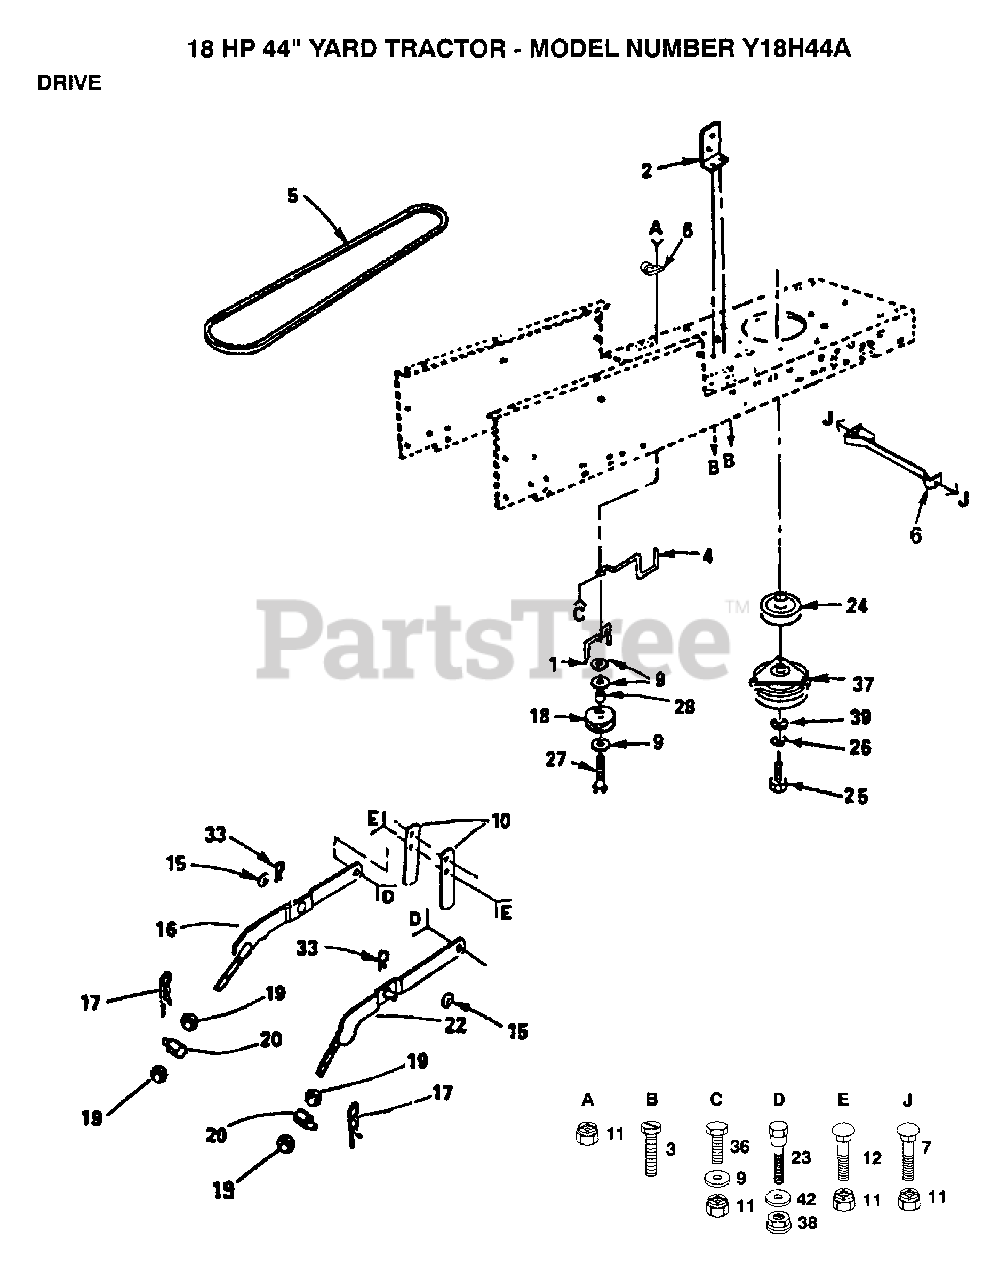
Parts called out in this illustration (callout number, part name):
1	BELT KEEPER LT
2	BRACKET LT
3	SCREW
4	KEEPER.BELT.ENG.L
7	BOLT
9	WASHER
10	UPSTOP
16	LH SUSP ARM ASM
17	SPRING H
18	PULLEY.IDLER.FLAT
19	NUT
22	RH SUSP ARM ASM
23	"BOLT, SHOULDER LT"
26	LOCKWASHER
27	BOLT
28	SPACER T
33	SPRING.RETAINER
36	BOLT
38	NUT SPECIAL T
39	WASHER
42	WASHER T
